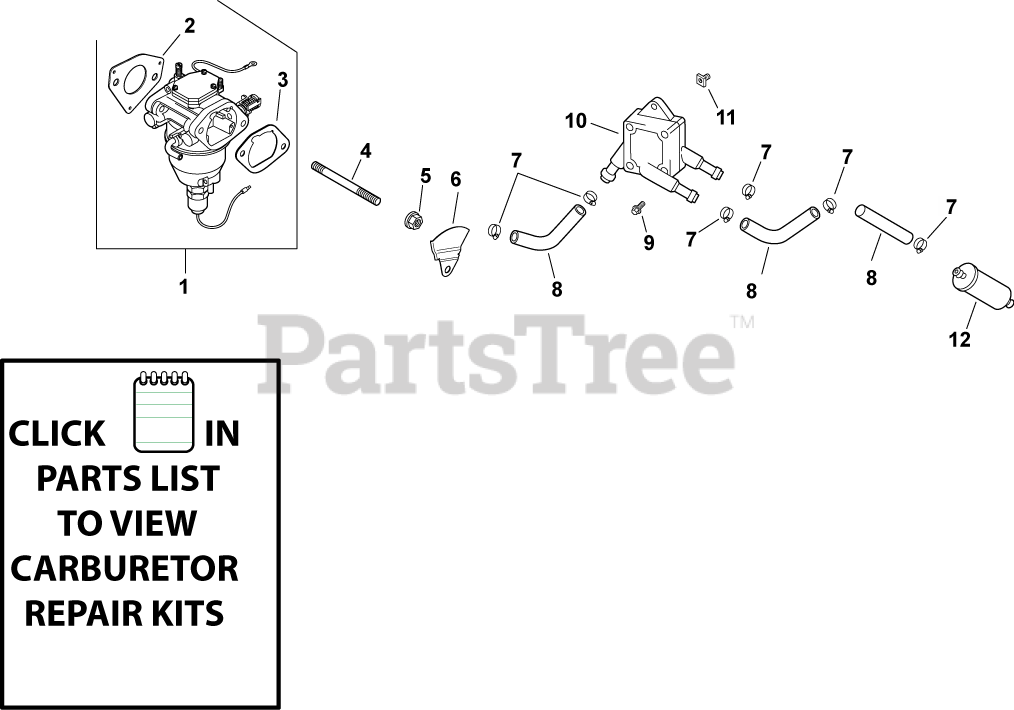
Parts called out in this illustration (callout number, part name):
1	KIT, CARBURETOR W/GASKET
2	GASKET, CARBURETOR
3	GASKET, AIR CLEANER BASE
4	STUD,M6X1.0X96
5	NUT, FLG M6X1.0
6	BAFFLE, SPIT-BACK CUP-USE 24 063 105-S
7	CLAMP, HOSE (KM)-USE 25 237 31-S
8	HOSE,LW PERM.FUEL 24.00"-USE 25 111 81-S
9	SCREW, TAP M6X1.7X18
10	PUMP, FUEL
11	NUT, PLASTIC - BLACK
13	FILTER, FUEL
